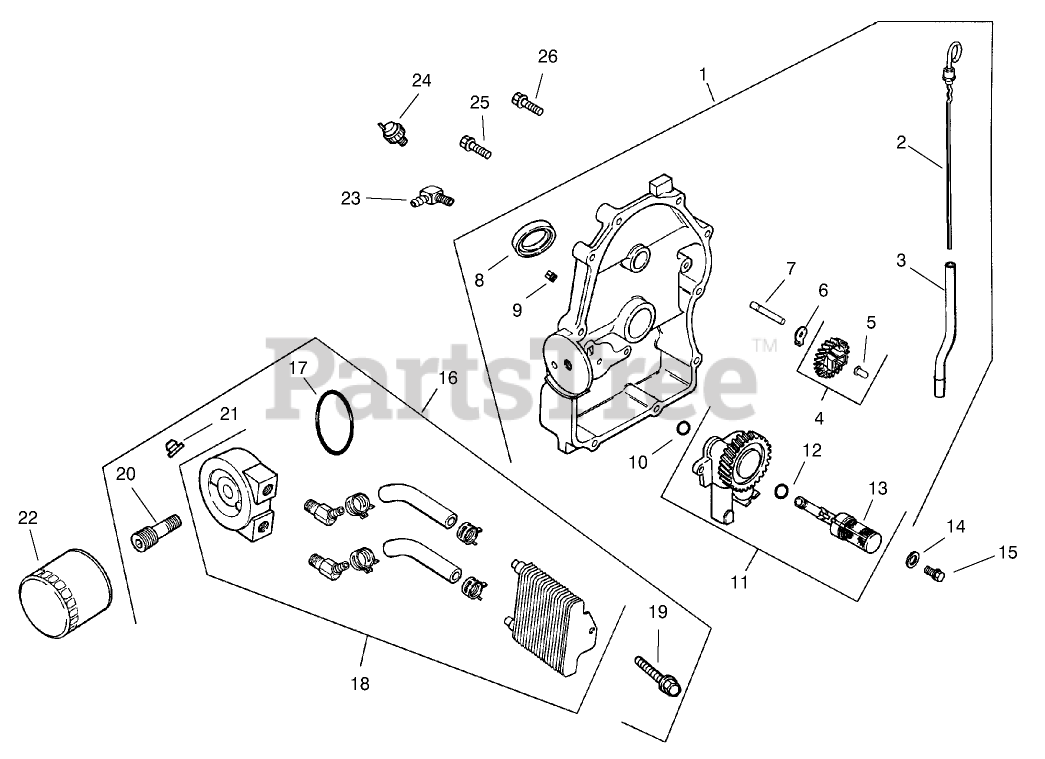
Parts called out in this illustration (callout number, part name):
1	Closure Plate ASM(Incl. Ref.# 2-12)
2	Dipstick
3	Tube-Dipstick
4	Kit-Gear, Governor (Incl. Ref.# 5)
5	Pin-Governor
6	Tab-Locking
7	Shaft-Gear, Governor
8	Seal-Oil
9	Plug
10	O Ring
11	Oil Pump ASM(Incl. Ref.# 12,13)
12	O-Ring
13	Pick Up-Oil
14	Washer
15	Screw
16	Kit-Cooler, Oil(Incl. Ref.# 17-21)
17	O-Ring
18	Cooler-Oil
19	Screw
20	Nipple, oil filter
21	Nut
22	Filter-Oil
23	Connector
24	Switch-Pressure
25	Screw
26	Screw
